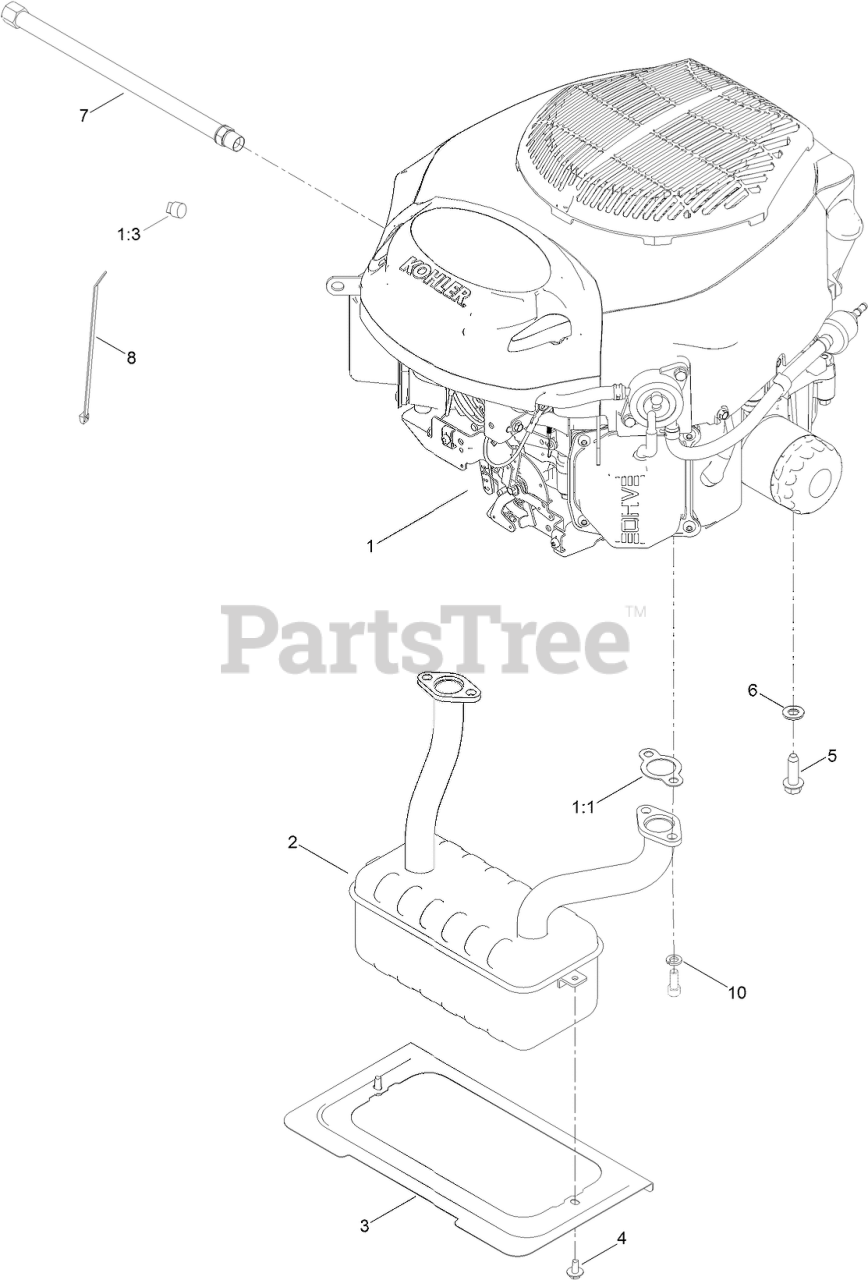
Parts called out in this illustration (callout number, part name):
1	ENGINE-KOHLER 22 HP 7000 SERIES CARB
1:1	GASKET-EXHAUST
1:3	PLUG-PIPE, SQH
2	MUFFLER
3	SHIELD-HEAT
4	SCREW-HHFTF
5	SCREW-TAPTITE
6	WASHER-FLAT
7	HOSE-DRAIN, OIL
8	TIE-CABLE
10	WASHER-LOCK
